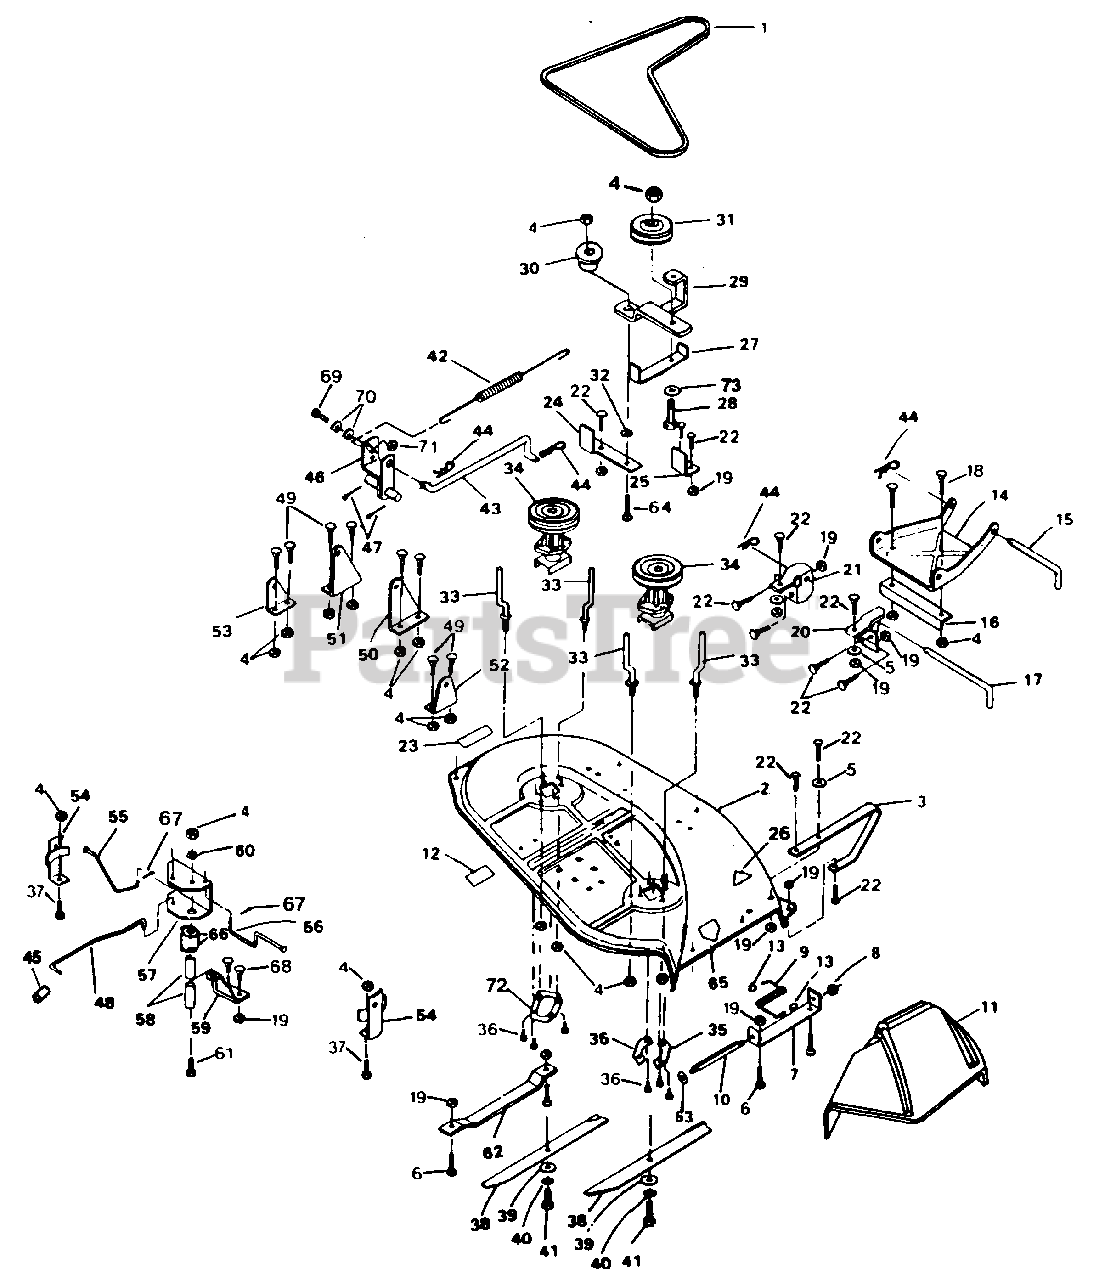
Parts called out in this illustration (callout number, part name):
1	V-Belt (AYP part number)
2	Housing (AYP part number)
3	R.H. Runner (AYP part number)
4	Crownlock Nut
5	Washer (AYP part number)
6	Carriage Bolt (AYP part number)
7	Deflector Bracket (AYP part number)
8	Pushnut (AYP part number)
9	Deflector Spring (AYP part number)
10	Hinge Rod (AYP part number)
11	Shield Deflector (AYP part number)
12	V-Belt Mower Drive Decal (AYP part number)
13	Cap (AYP part number)
14	Parallel Link (AYP part number)
15	Front Hinge Pin (AYP part number)
16	Link Stop (AYP part number)
17	Rear Hinge Pin (AYP part number)
18	Bolt (AYP part number)
19	Crownlock Nut
20	R.H. Lift Bracket (AYP part number)
21	L.H. Lift Bracket (AYP part number)
22	Carriage Bolt
23	Caution Instruction Decal (AYP part number)
24	Arm Support (AYP part number)
25	Front Deck Stop (AYP part number)
27	Belt Guide (AYP part number)
28	Bolt (AYP part number)
29	Idler Arm (AYP part number)
30	Retainer Spacer (AYP part number)
31	Idler Pulley (AYP part number)
32	Wear Washer (AYP part number)
33	Keeper Belt (AYP part number)
34	Mandrel Assembly (AYP part number)
35	Mandrel Support Plate (AYP part number)
36	Washer Hd. Hex Screw (AYP part number)
37	Washer Hd. Hex Screw (AYP part number)
38	Blade
39	Washer (AYP part number)
40	Washer (AYP part number)
41	Hex Bolt (AYP part number)
42	Extension Spring (AYP part number)
43	Mower Clutch Rod (AYP part number)
44	Retainer Spring (AYP part number)
45	Cotter Pin (AYP part number)
46	Rock Shaft Assembly (AYP part number)
47	Cotter Pin (AYP part number)
48	Primary Brake Rod (AYP part number)
49	Carriage Bolt (AYP part number)
50	R.H. Pivot Bracket (AYP part number)
51	L.H. Pivot Bracket (AYP part number)
52	R.H. Rear Bracket Suspension (AYP part number)
53	L.H. Rear Bracket Suspension (AYP part number)
54	Brake Assembly (AYP part number)
55	L.H. Secondary Brake Rod (AYP part number)
56	R.H. Secondary Brake Rod (AYP part number)
57	Pivot Brake Bracket (AYP part number)
58	Brake Spacer (AYP part number)
59	Support Bracket (AYP part number)
60	Washer (AYP part number)
61	Bolt (AYP part number)
62	L.H. Runner (AYP part number)
63	Washer (AYP part number)
64	Bolt (AYP part number)
65	Warning Decal (AYP part number)
66	Spacer (AYP part number)
67	Cotter Pin (AYP part number)
68	Carriage Bolt (AYP part number)
69	Hex Bolt (AYP part number)
70	Special Washer (AYP part number)
71	Crownlock Washer (AYP part number)
72	L.H. Mandrel Support (AYP part number)
73	Washer (AYP part number)
